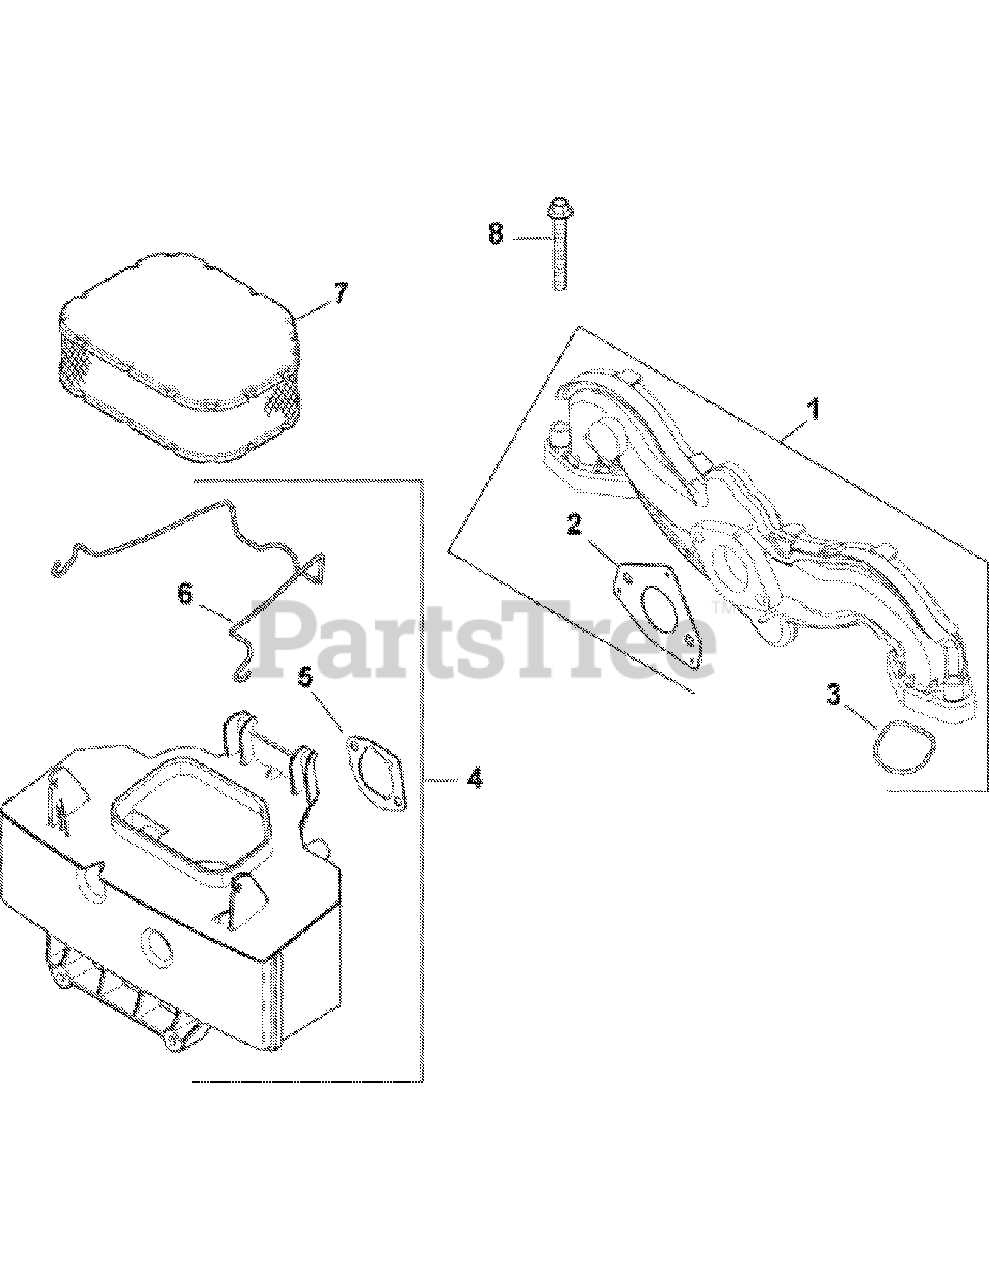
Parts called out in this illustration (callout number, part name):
1	KIT, INTAKE MANIFOLD
2	GASKET, CARBURETOR
3	O-RING, INTAKE PORT
4	KIT, AIR CLEANER BASE
5	GASKET, AIR CLEANER BASE
6	LATCH, AIR CLEANER ELEMENT
7	ELEMENT, AIR FILTER
8	SCREW, FLG M6X1.0X40
